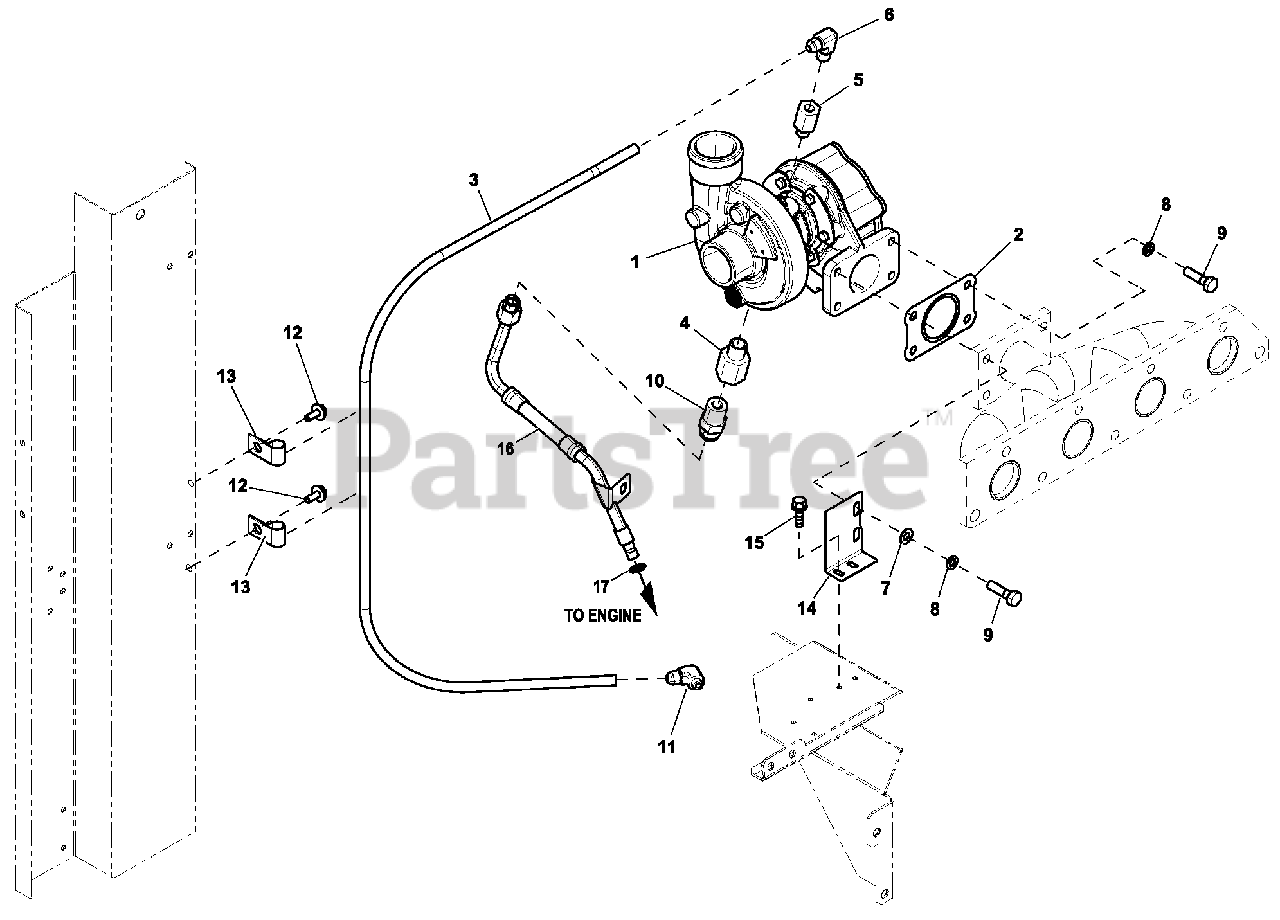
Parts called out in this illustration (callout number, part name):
1	ASSY RGLTR INLET NPT FITTINGS
2	REGULATOR ASSY 2.4L 36KW
3	GASKET, BOSCH 32 & 40
4	ACTUATOR BOSCH 40, GOVERNOR
5	ELBOW RUBBER 90 2" ID
6	INTAKE TUBE 2.4L G2 36KW
7	HOSE COOLING 2IN ID 20R4 (2IN)
8	MIXER ACTUATOR
9	BOLT U 5/16-18X2.09
10	BRACKET INTAKE MANIFOLD
11	SCREW HHTT M6-1.0 X 12
12	CLAMP CNST TENSION 1.75-2.625
13	HOSE 3/4 ID SAE-30R2 (35"LG)
14	CLAMP HOSE #8 .53-1.00
15	CLAMP HI TORQUE 1.75 - 2.625
16	BRACKET-INTAKE REINFORCEMENT
17	WASHER LOCK M6-1/4
18	SCREW SHC M6-1.0 X 50 C8.8
19	WASHER FLAT 5/16-M8 ZINC
20	SCREW HHC M8-1.25 X 20 G8.8
21	VENTURI THROTTLE 24MM
22	O-RING 47.625 ID X 2.38 WIDTH
23	O-RING 45.63 ID X 2.62 WIDTH
24	WASHER LOCK M8-5/16
25	NUT HEX 5/16-18 STEEL
26	BARBED STR 1/2NPTX3/4
27	HEX NUT-METRIC
28	SCREW HHC M8-1.25 X 16 G8.8
29	SADDLE 2 INCH
30	HARN FUEL JUMPER SINGLE REG
